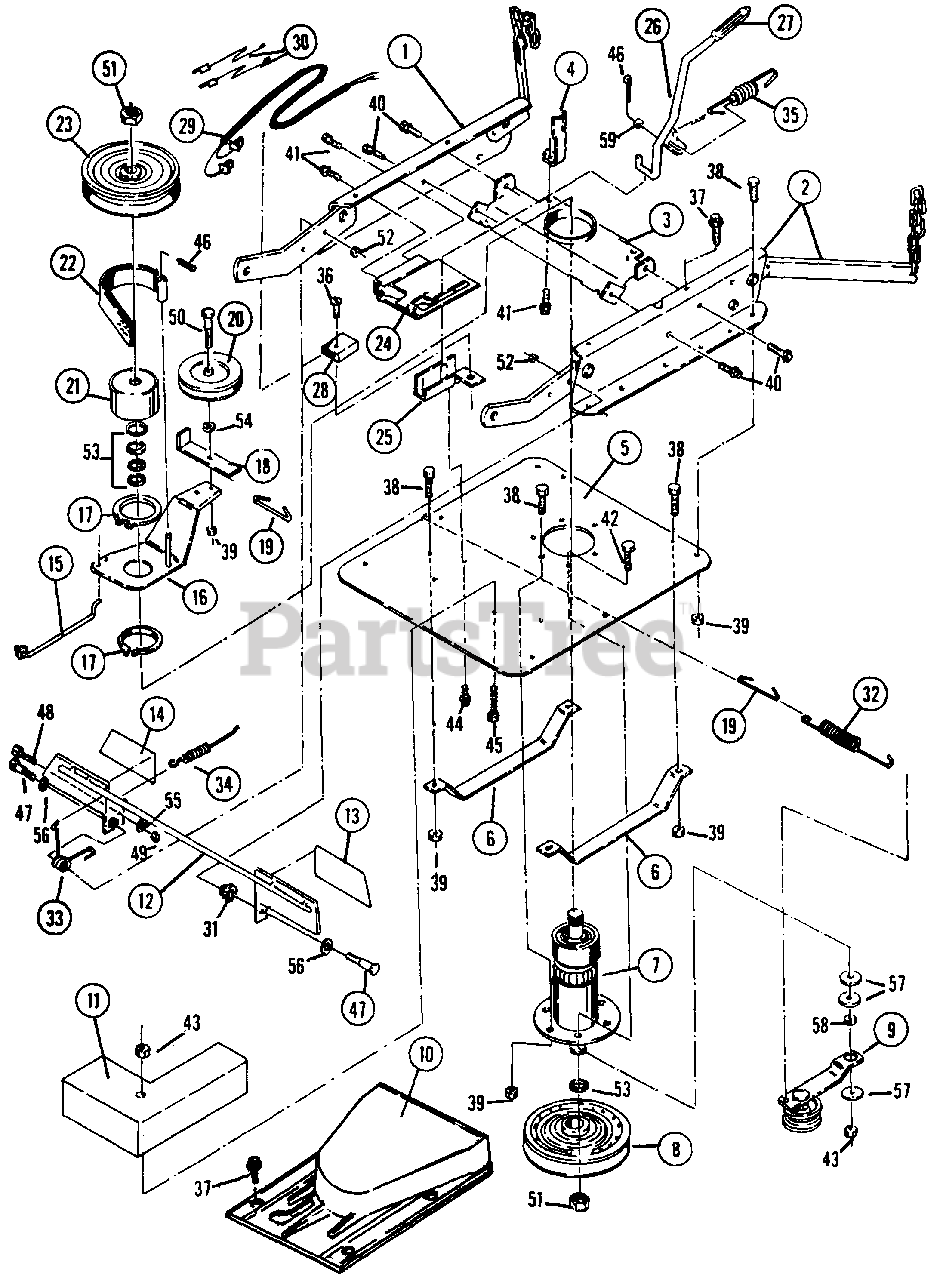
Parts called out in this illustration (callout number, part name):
1	RAIL ASSEMBLY, Right Side
2	RAIL ASSEMBLY, Left Side
3	BRACE, Rail Top
4	GUIDE, Belt
5	PLATE, Spindle Mounting
6	RUNNER
7	SPINDLE ASSEMBLY
8	PULLEY, 8.36" O.D.
9	IDLER ARM ASSEMBLY
10	COVER, SPINDLE
11	WEIGHT, Carrier
12	PEDAL, Blade/Auger
13	TREAD, Blade Stop-Left Side
14	TREAD,Blade Stop-Right Side
15	ROD, Idler
16	ARM, Idler
17	RING, 2" External Retaining
18	RESTRICTOR, Belt
19	LINK, Wire
20	PULLEY, Idler
21	DRUM, Brake
22	BAND, Brake
23	PULLEY, Spindle
24	CLUTCH-PLATE ASSEMBLY
25	MOUNT, Blade Handle
26	HANDLE, Blade
27	GRIP, Handle
28	SWITCH, Interlock
29	HARNESS, Wiring
30	CONNECTOR-LEADS
31	BEARING, Nylon
32	SPRING
33	SPRING
34	SPRING
35	SPRING
36	SCREW, 10-32x1 Self Tap
37	SCREW, 1/4-20x5/8 Self Tap
38	SCREW, 3/8-24x3/4 Hex Head Cap
39	LOCKNUT, 3/8-24 Hex
40	SCREW, 3/8-16x1 Self Tap
41	SCREW, 5/16-18x5/8 Self Tap
42	SCREW, 5/16Fx1-1/4 Hex Head Cap
43	LOCKNUT, 5/16-24 Hex
44	SCREW, 1/4-20x5/8 Self Tap
45	SCREW, 5/16-24x3-3/4 Hex Head Cap
46	COTTER-PIN, 3/32x3/4
47	BOLT, 3/8-24x1-3/4 Shoulder
48	SCREW, 1/4-28x1 Hex Head Cap
49	NUT, 1/4-28 Hex
50	SCREW, 3/8-24x1-3/4 Hex Head Cap
51	NUT, 3/4-16 Hex Jam
52	NUT, 3/8-24 Hex
53	WASHER, Spacer
54	WASHER, 3/8 SAE
55	LOCKWASHER, 1/4 Internal Tooth
56	WASHER, 1/2 SAE
57	WASHER, 5/16" x 1-1/4" x 3/32" Flat
58	SPACER
59	WASHER, 1/4 SAE
